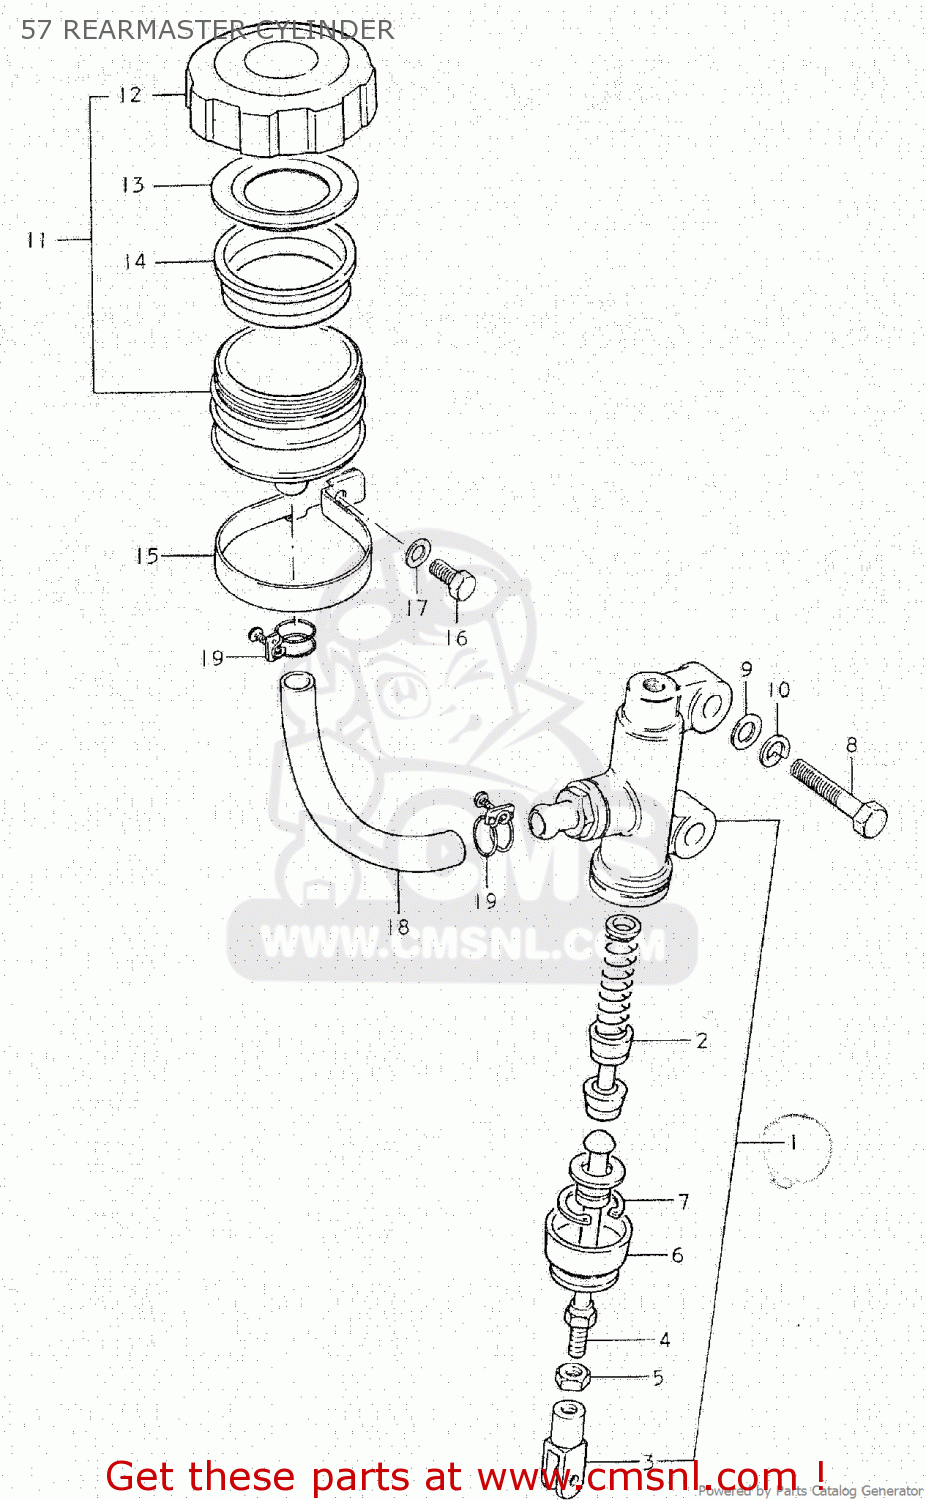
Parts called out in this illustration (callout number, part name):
1	CYLINDER ASSEMBLY,REAR MASTER
2	PISTON/CUP SET
3	YOKE
4	ROD,PUSH
5	NUT
6	BOOT
7	CIRCLIP
8	BOLT (8X30)
9	WASHER
10	LOCK WASHER
11	TANK ASSEMBLY,RESERVOIR
12	CAP
13	PLATE,DIAPHRAGM
14	DIAPHRAGM
15	CLAMP
16	BOLT
17	WASHER 6MM
18	HOSE,RESERVOIR TANK
19	CLAMP
